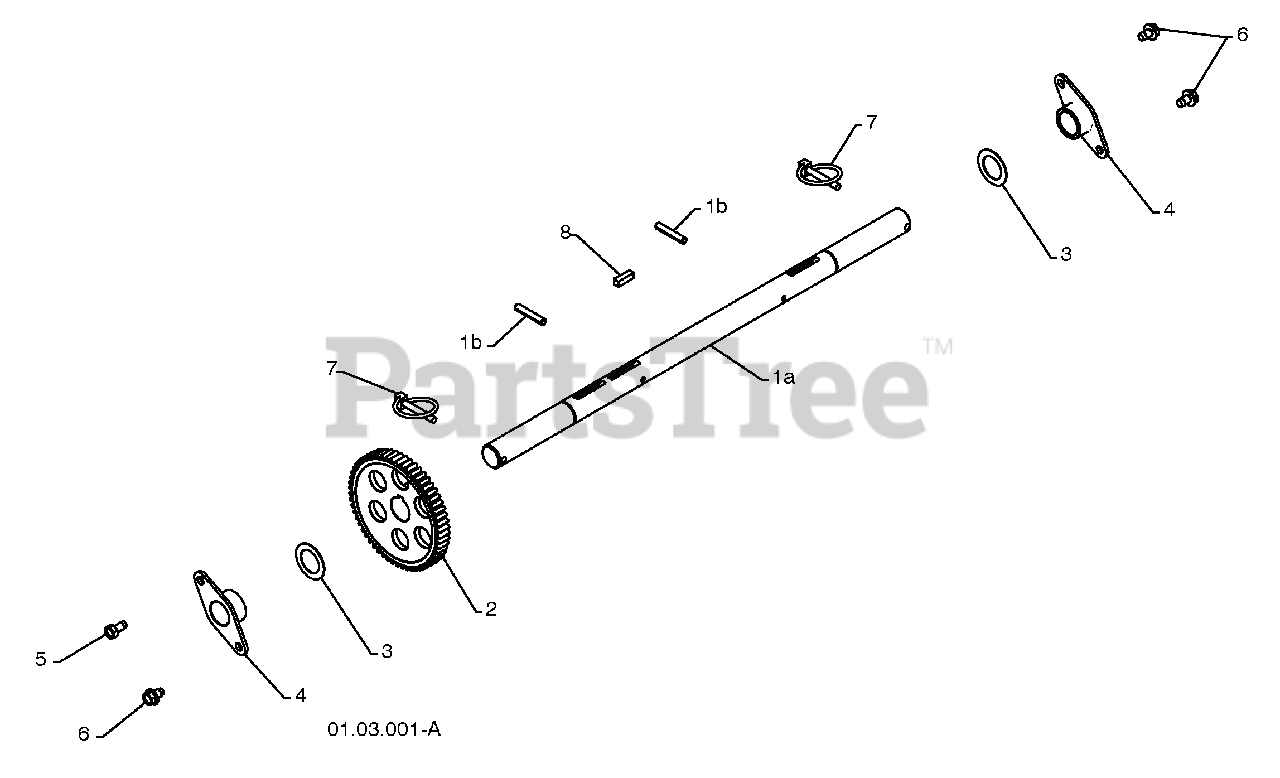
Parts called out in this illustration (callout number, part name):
1	(assy of 1a,1b) AXLE ASSEMBLY
2	GEAR
3	THRUST WASHER
4	AXLE BEARING
5	SCREW 5/16-18 X .625
6	BOLT 5/16-18 X .500
8	SQUARE KEY
